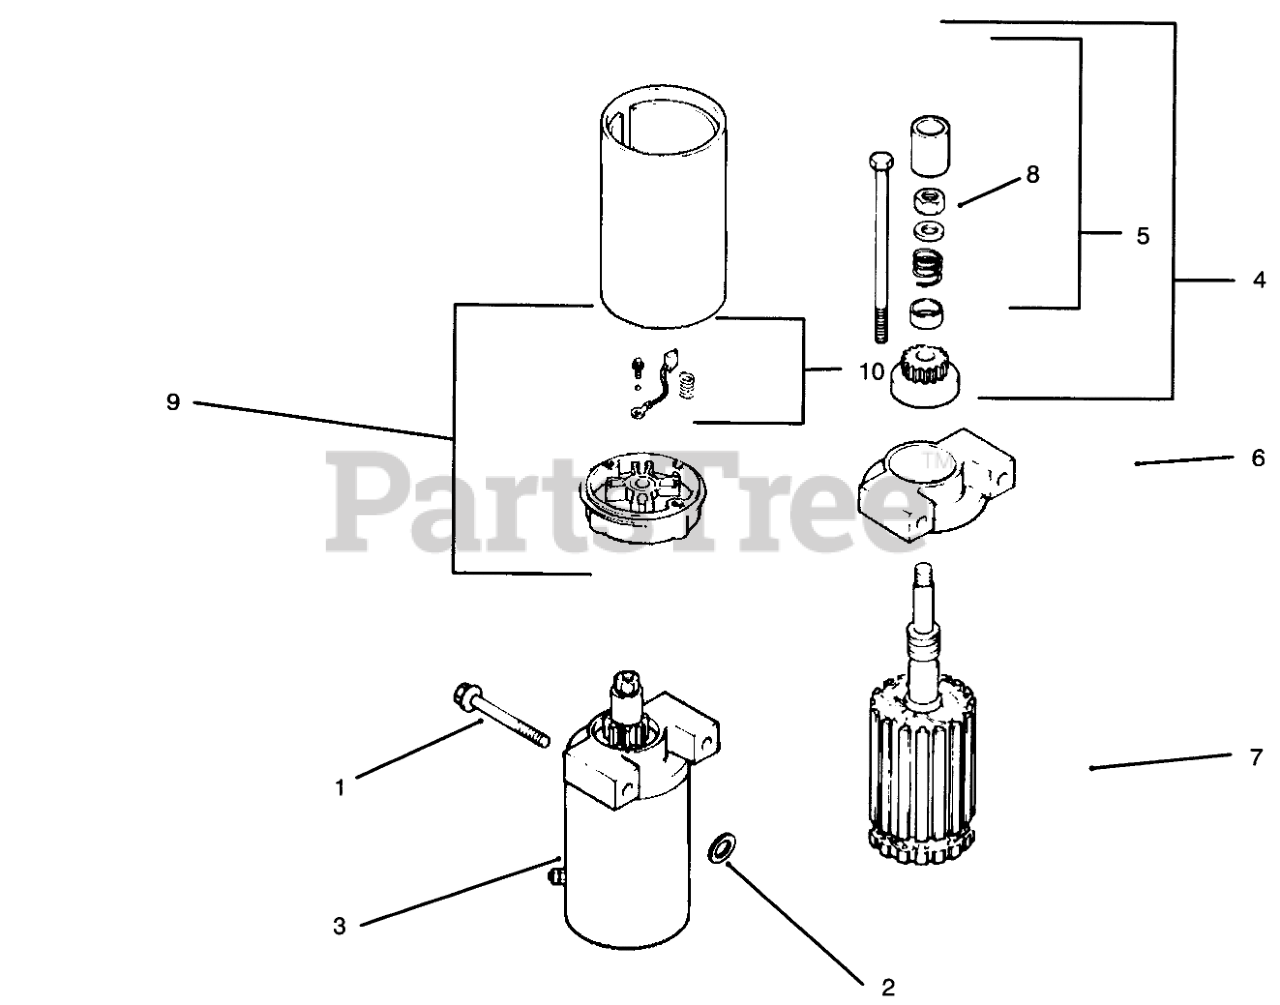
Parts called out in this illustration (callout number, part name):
2	Washer
3	Starter (Incl. Ref. #4-10)
4	Kit-Drive (Incl. Ref. #5)
5	Kit
6	Cap-Drive End
7	Armature
8	Screw-Flange
9	Cap-Commutator End
10	Kit-Brush
